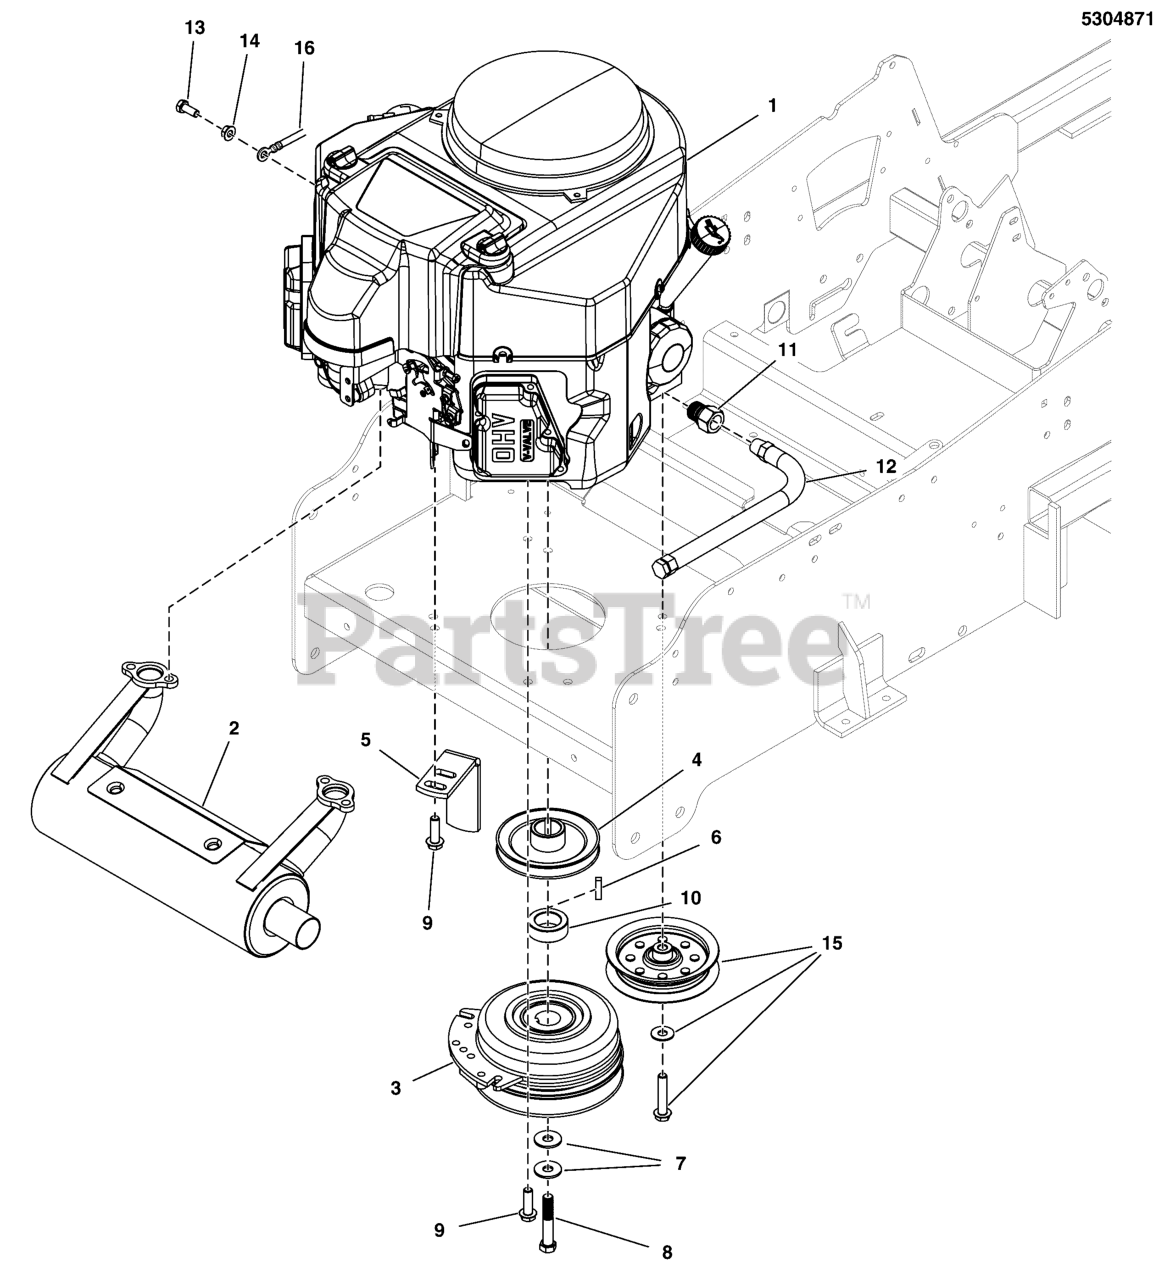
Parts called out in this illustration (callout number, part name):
1	ENGINE, 19HP, KAWASAKI, FX600V
2	MUFFLER, (16-20HP), KAWASAKI S50X
3	CLUTCH, WARNER, 125 FT LBS, 1-1/8" BORE
4	PULLEY, PUMP DRIVE, 4.857 OB X 1-1/8
5	ANCHOR, CLUTCH - BLK
6	KEY, 1/4 SQ X 1
7	BELLEVILLE WASHER, 1.1875 X .442 X .098
8	BOLT, CRANKSHAFT, 7/16 X 2-3/4, PATCH, CZ
9	BOLT, HEX FLG, SER, GD5 3/8-16 X 1-1/4" PACH CZ
10	SPACER, 1.13 X 1.75 X .75, CZ
11	ADAPTER, Oil Drain
12	HOSE, OIL DRAIN
13	BOLT, M8-1.25 X 20 MM GD 8.8
14	NUT, M8-1.25 Hex Serrated Flange
15	SEE TRANSAXLE DRIVE GROUP
16	SEE ELECTRICAL GROUP
